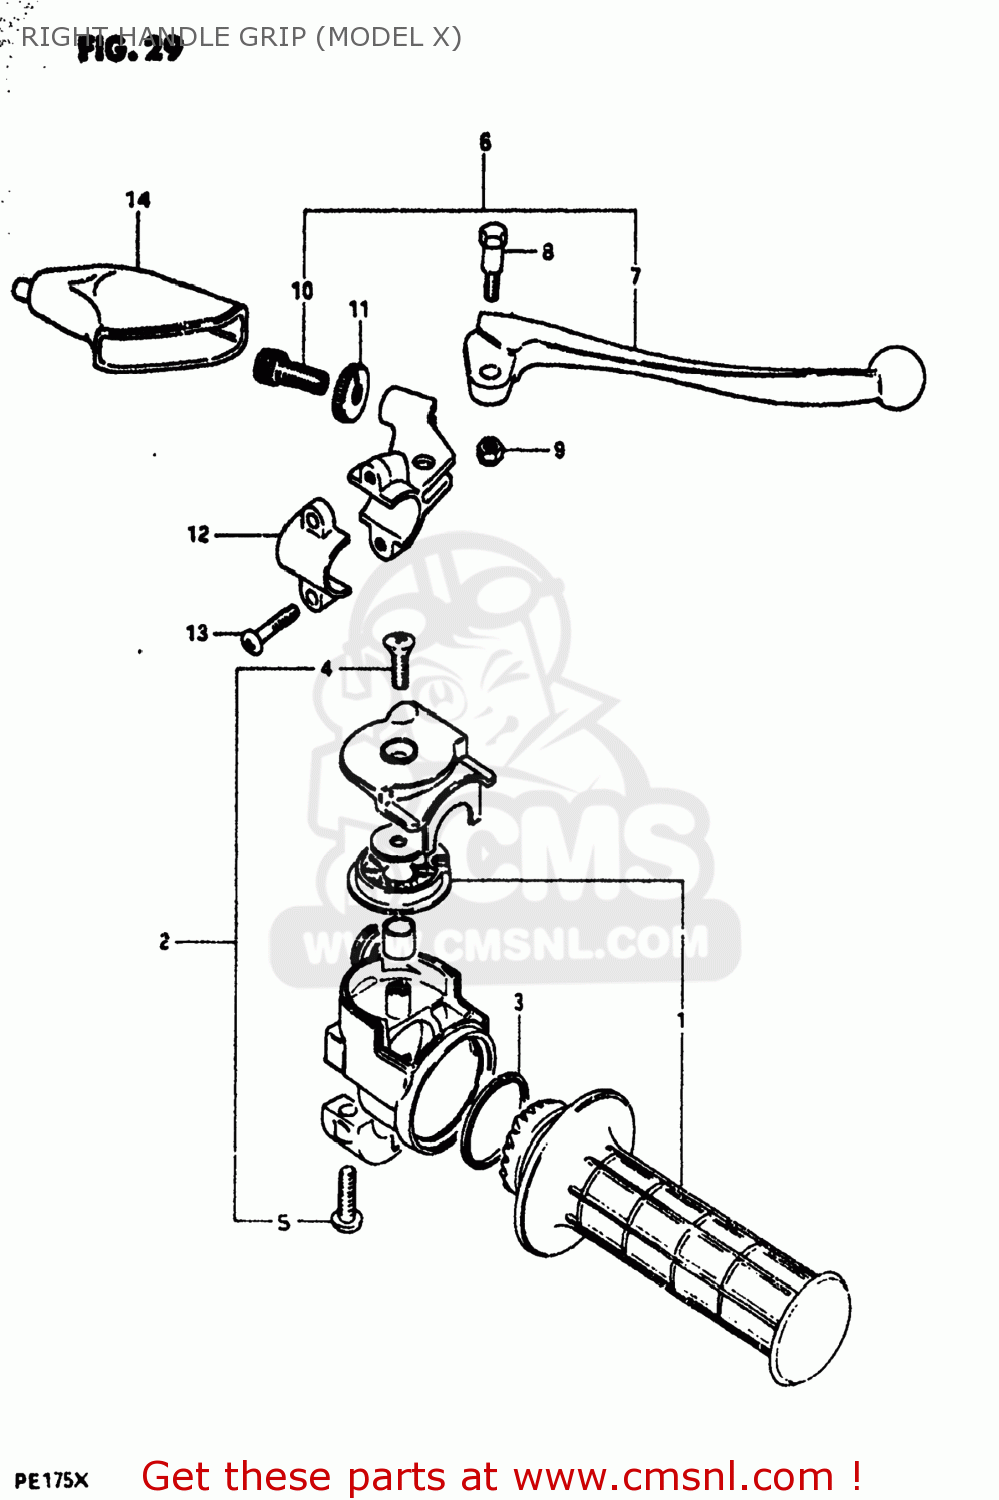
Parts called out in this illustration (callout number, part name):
1	GRIP SET,THROTTLE
2	CASE ASSY,THROTTLE
3	V-RING,THROTTLE GRIP
4	SCREW
5	SCREW 5X20
6	LEVER ASSEMBLY,BRAKE
7	LEVER,BRAKE
8	BOLT,LEVER
9	NUT 6MM
10	ADJUSTER,CABLE
11	NUT,CABLE ADJUSTER
12	BRACKET,LEVER
13	SCREW
14	COVER,CLUTCH LEVER
